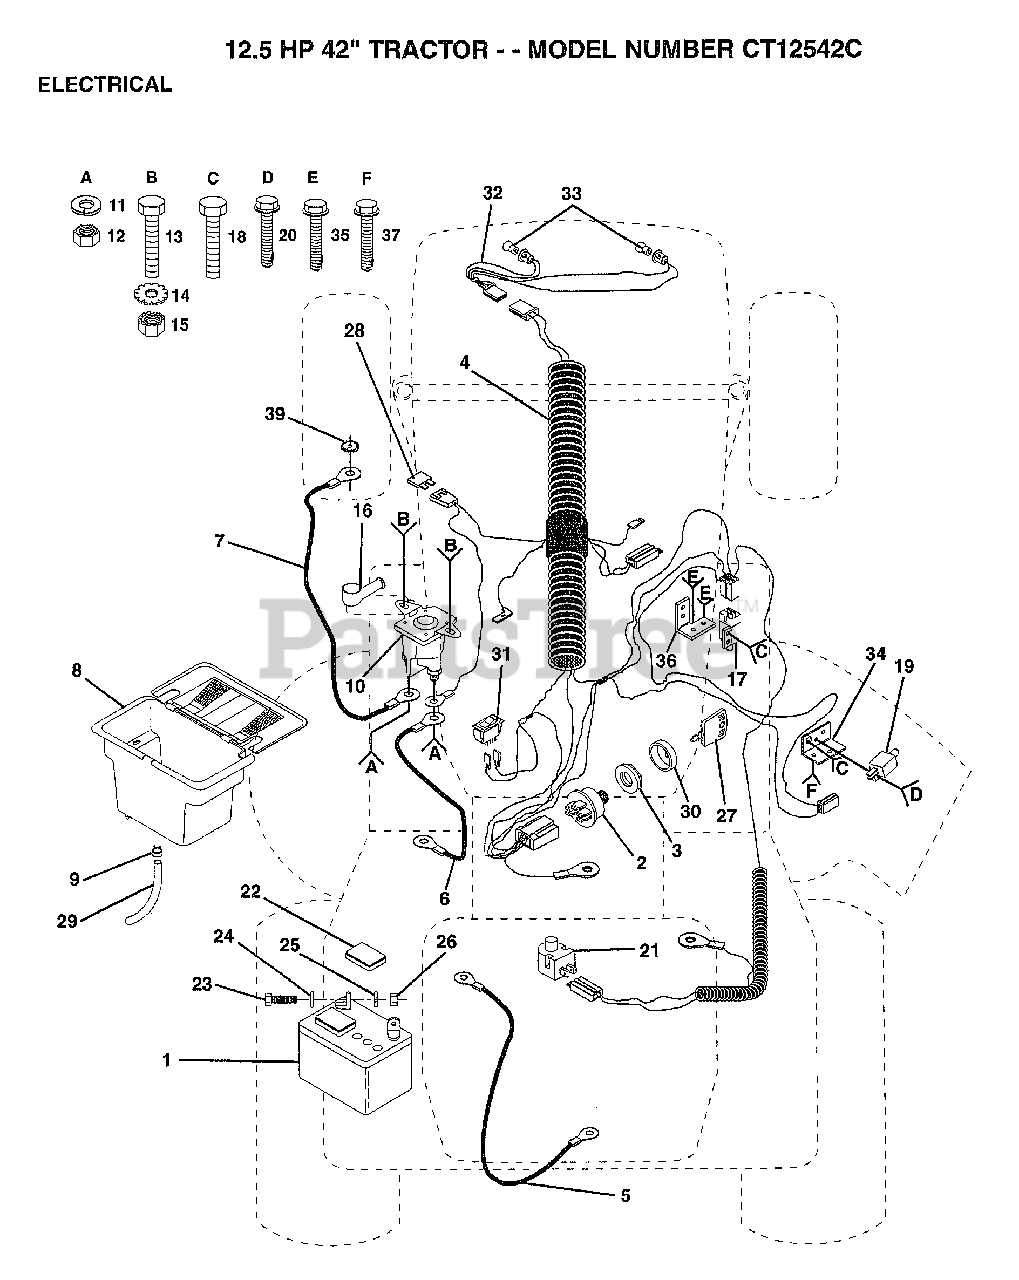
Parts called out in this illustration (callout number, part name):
3	NUT IGNITION
4	IGN HARNESS
5	CABLE T
7	"CABLE T, BATTERY"
9	HOSE CLAMP T
12	NUT
13	BOLT
15	NUT
17	SWITCH INTERLOCKT
18	SCREW
19	SWITCH-INTER. GT
20	SCREW
21	SWITCH SEAT
22	"CAP,BATTERY "
23	BOLT LT
24	WASHER
25	LOCKWASHER
28	FUSE HYT
29	TUBE T
31	SWITCH LT
32	"HARNESS,LIGHT SOC"
34	BRACKET LT
35	SCREW
36	SWITCH BRACKET
37	SCREW
39	LOCKWASHER
